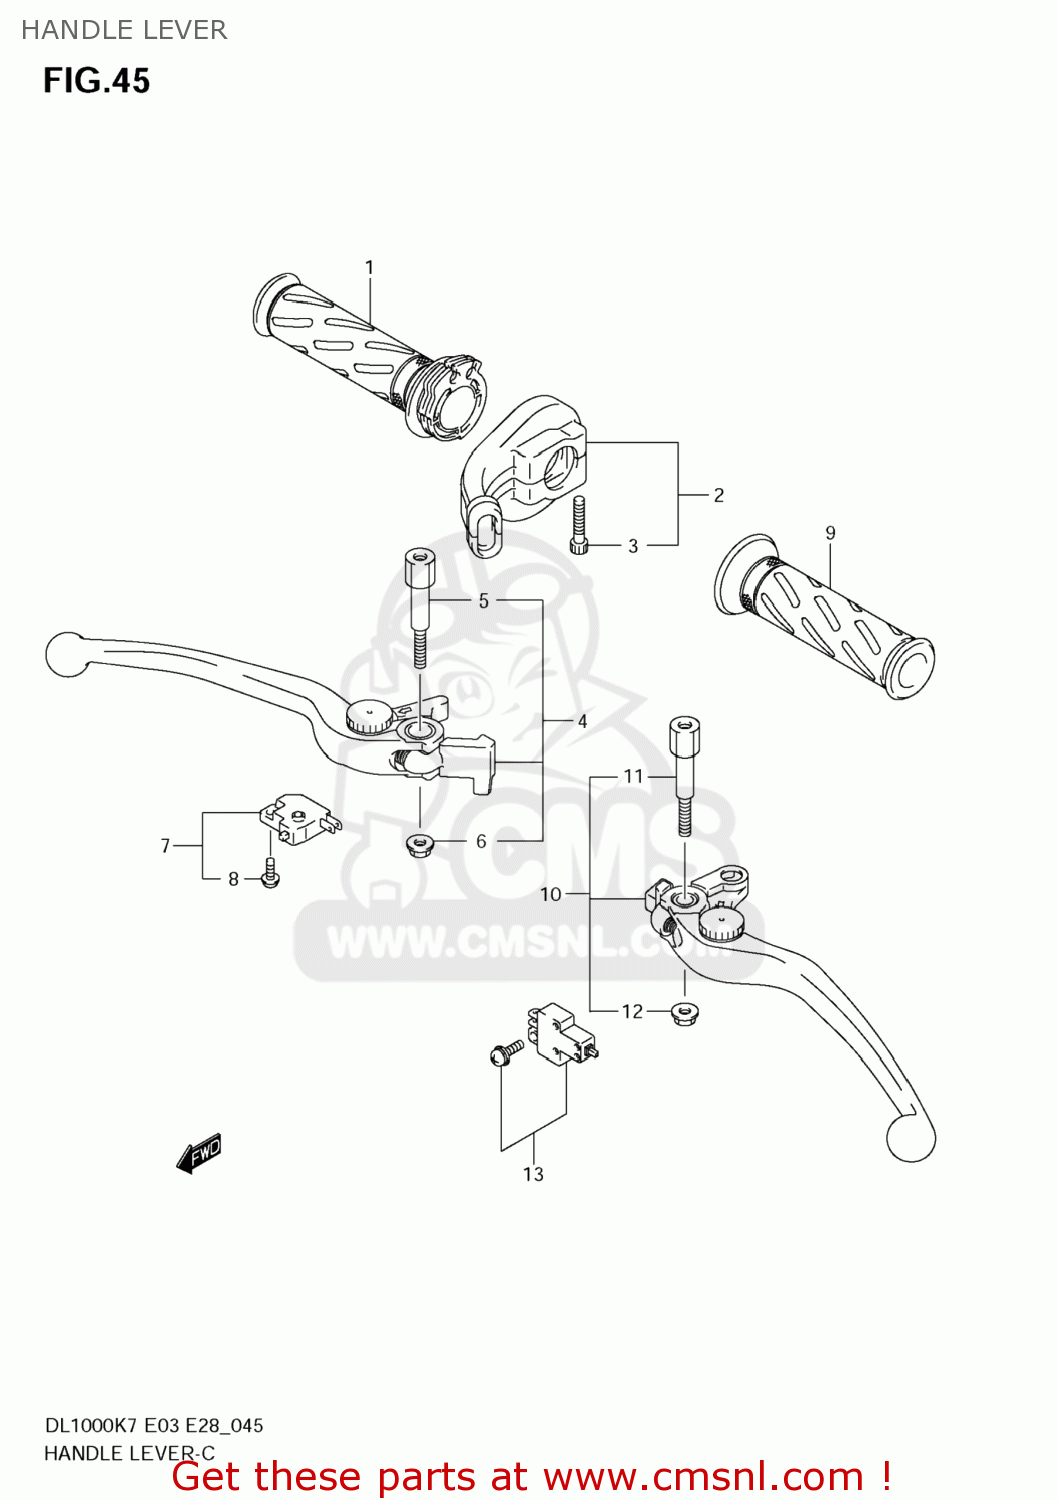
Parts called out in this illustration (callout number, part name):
1	GRIP,THROTTLE
2	CASE ASSY,THROTTLE
3	BOLT
4	LEVER ASSY,BRAKE
5	BOLT,LEVER
6	NUT
7	SWITCH ASSY,ST
8	SCREW
9	GRIP,LEFT
10	LEVER ASSY,CLUTCH
11	BOLT,LEVER PIVOT
12	NUT
13	SWITCH ASSY,CLUTCH
